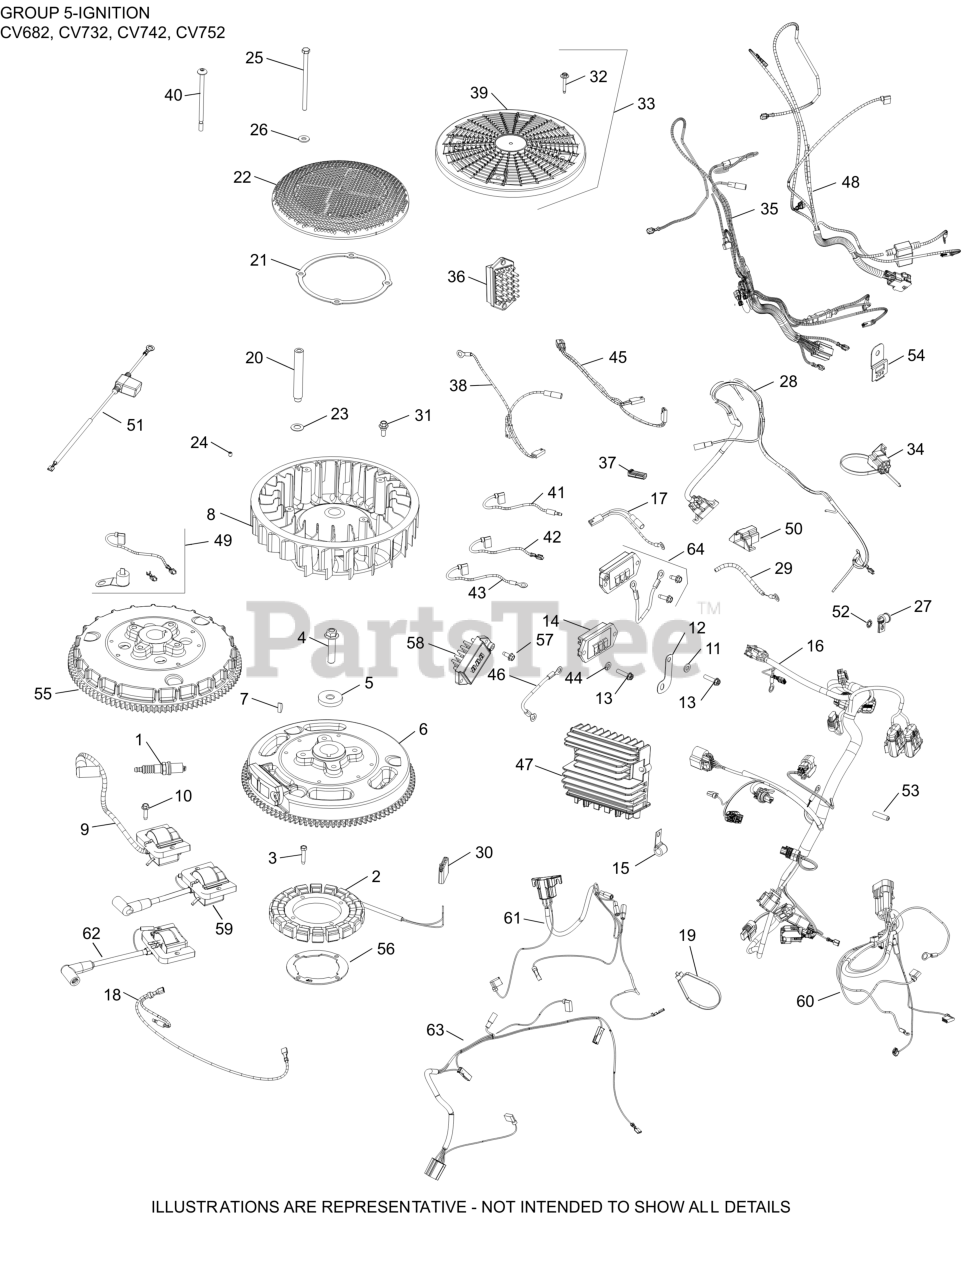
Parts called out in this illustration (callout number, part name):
1	SPARK PLUG, RFI
2	KIT, 15 / 20 AMP STATOR
3	SCREW, THREAD FORMING
4	SCREW, HEX FLANGE
5	WASHER, FLAT
7	KEY, 3/16" X 5/8"
9	MODULE, MAGNETO DIGITAL IGNITION
10	SCREW, THREAD FORMING
11	WASHER, FLAT 1/4" (O.D. 1/2")
13	SCREW, HEX FLANGE HI-LO
15	CLIP, CABLE
18	HARNESS, LEAD DUPLEX
21	RING, SUPPORT
22	SCREEN, GRASS
23	WASHER, SPRING 10 MM
24	SCREW, SKT SET #10-24X1/4"
25	SCREW, CAP M6X1.0X99.5
26	WASHER, FLAT 1/4" (O.D. 5/8")
30	CONNECTOR
35	HARNESS, WIRING ASSEMBLY
38	LEAD, JUMPER V/S
52	WASHER, INT TOOTH LOCK 1/4"
57	SCREW, THREAD FORMING
NI	FLYWHEEL ASSEMBLY (LW)
NI	REGULATOR, RECTIFIER (20-30AMP,FW W/OVP)
